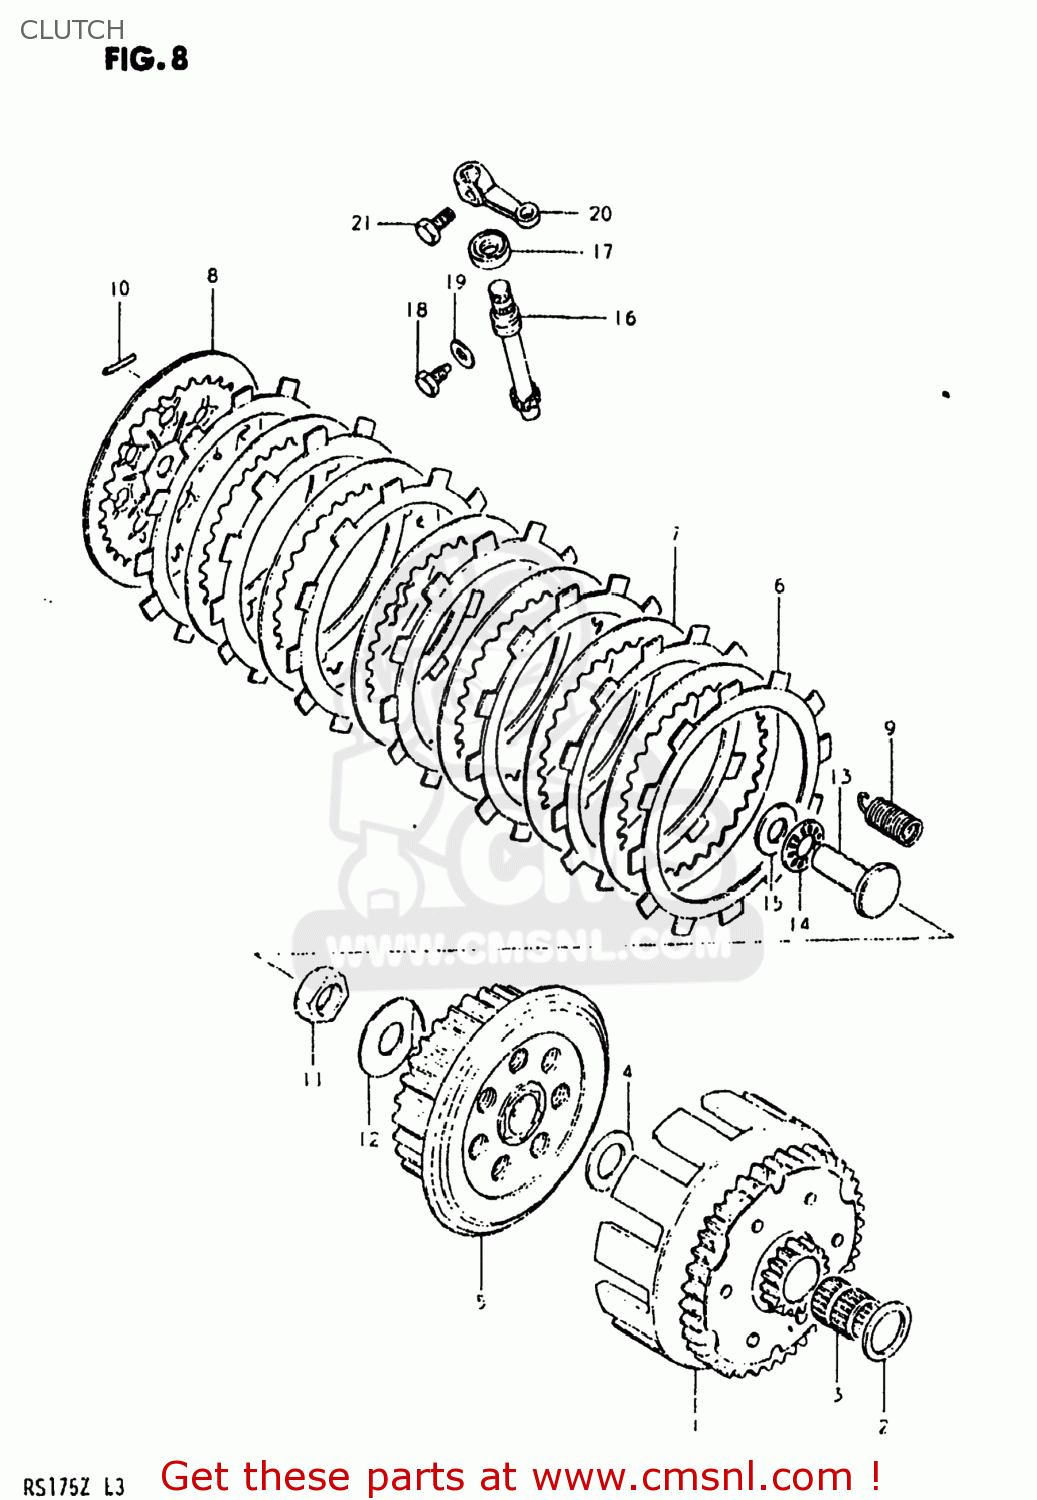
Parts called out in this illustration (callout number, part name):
1	GEAR ASSEMBLY,PRIMARY DRIVE
2	WASHER
3	BEARING(20X25X26)
4	WASHER
5	HUB,CLUTCH SLEEVE
6	PLATE,CLUTCH DRIVE
7	PLATE,CLUTCH DRIVEN
8	PLATE,CLUTCH PRESSURE
9	SPRING
10	PIN(2.5X19.8)
11	NUT
12	WASHER,LOCK
13	RACK,CLUTCH RELEASE
14	BEARING(10X22X2.8)
15	WASHER(10.1X21.4X0.8)
16	PINION,CLUTCH RELEASE
17	SEAL,OIL (10X17X5)
18	BOLT(6X12)
19	WASHER
20	ARM,CLUTCH RELEASE
21	BOLT, UPPER
